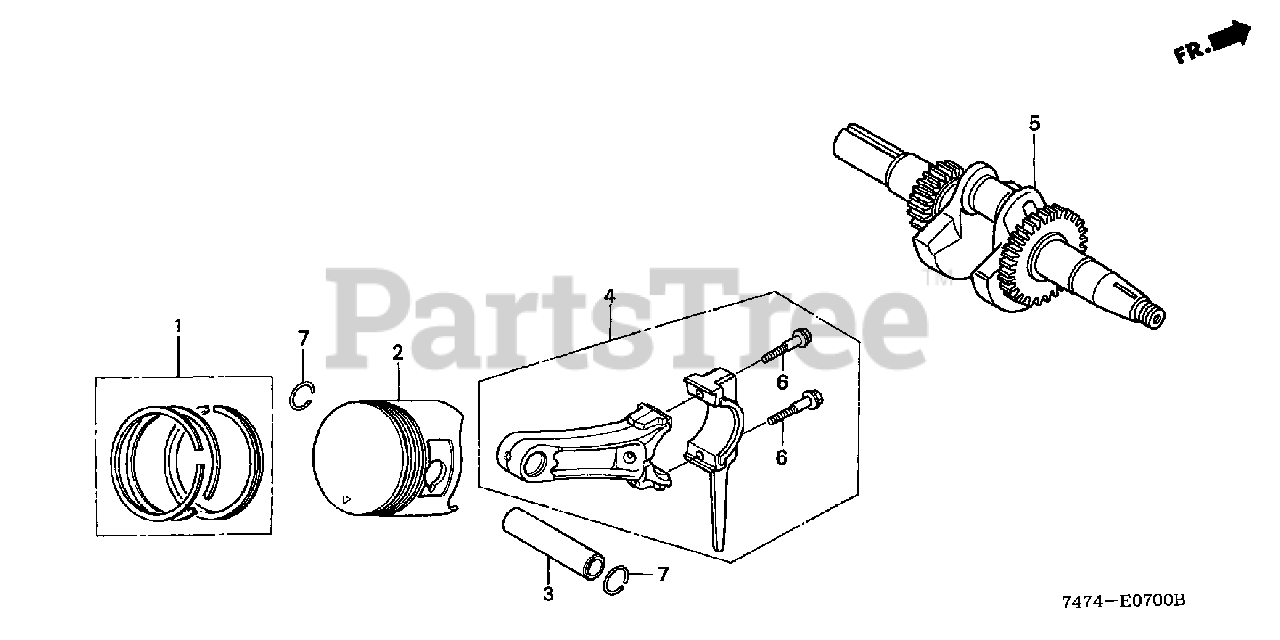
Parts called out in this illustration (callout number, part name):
1	RING SET, PISTON (STD)
1	RING SET, PISTON (STD) (NIPPON)
1	RING SET, PISTON (OS 0.25) Use up to Engine SN 7603338.
1	RING SET, PISTON (OS 0.25) Use from Engine SN 7603339.
1	RING SET, PISTON (OS 0.50) Use up to Engine SN 7603338.
1	RING SET, PISTON (OS 0.50) Use from Engine SN 7603339.
1	RING SET, PISTON (0.75) Use up to Engine SN 7603338.
1	RING SET, PISTON (0.75) Use from Engine SN 7603339.
2	PISTON (STD)
2	PISTON (OS 0.25)
2	PISTON (OS 0.50)
2	PISTON (0.75)
3	PIN, PISTON
4	ROD ASSY., CONNECTING (US 0.25)
4	ROD ASSY., CONNECTING
5	CRANKSHAFT (S-TYPE)
6	BOLT, CONNECTING ROD
7	CLIP, PISTON PIN (18MM)
